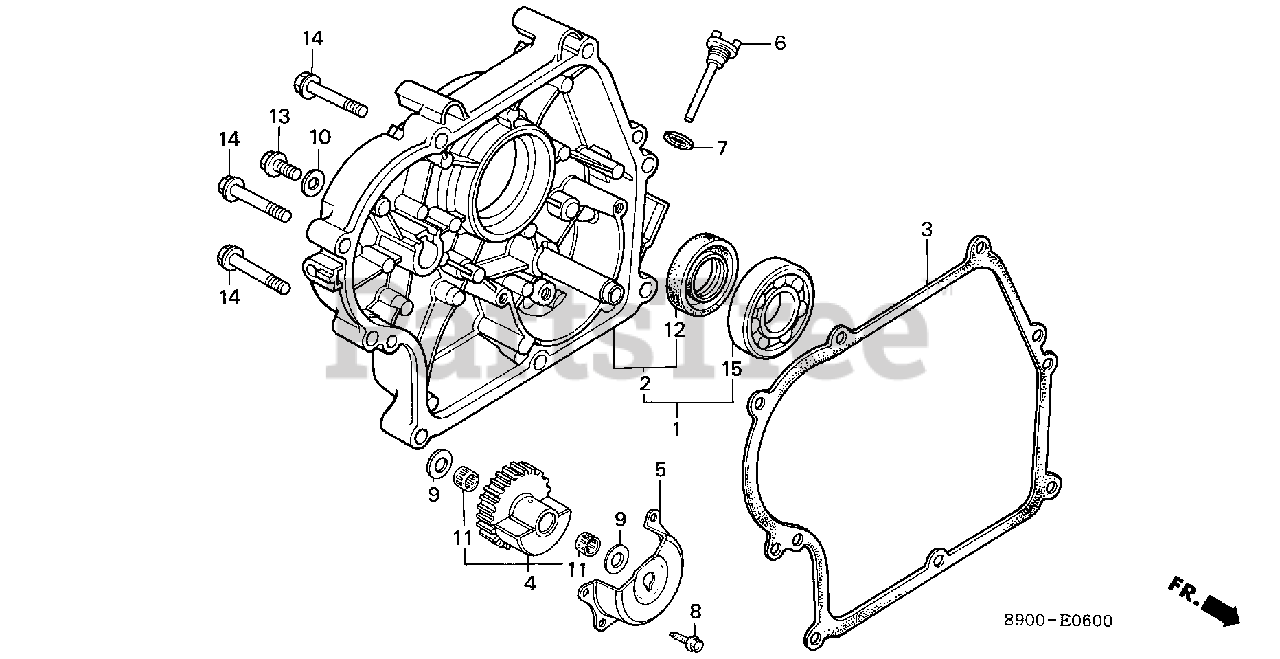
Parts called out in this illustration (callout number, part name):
1	COVER ASSY., CRANKCASE
2	COVER ASSY., CRANKCASE
3	GASKET, CASE COVER
4	WEIGHT, BALANCER
5	COVER, BALANCER
6	CAP, OIL FILLER (YELLOW)
8	BOLT, FLANGE (6X12) (CT200)
8	BOLT, FLANGE (6X16)
9	WASHER, THRUST (15MM)
10	WASHER A (8MM)
11	BEARING, NEEDLE
12	OIL SEAL (30X46X8)
13	BOLT, FLANGE (8X12)
13	BOLT, FLANGE (8X14)
14	BOLT, FLANGE (8X45)
15	BEARING, RADIAL BALL (6206)
